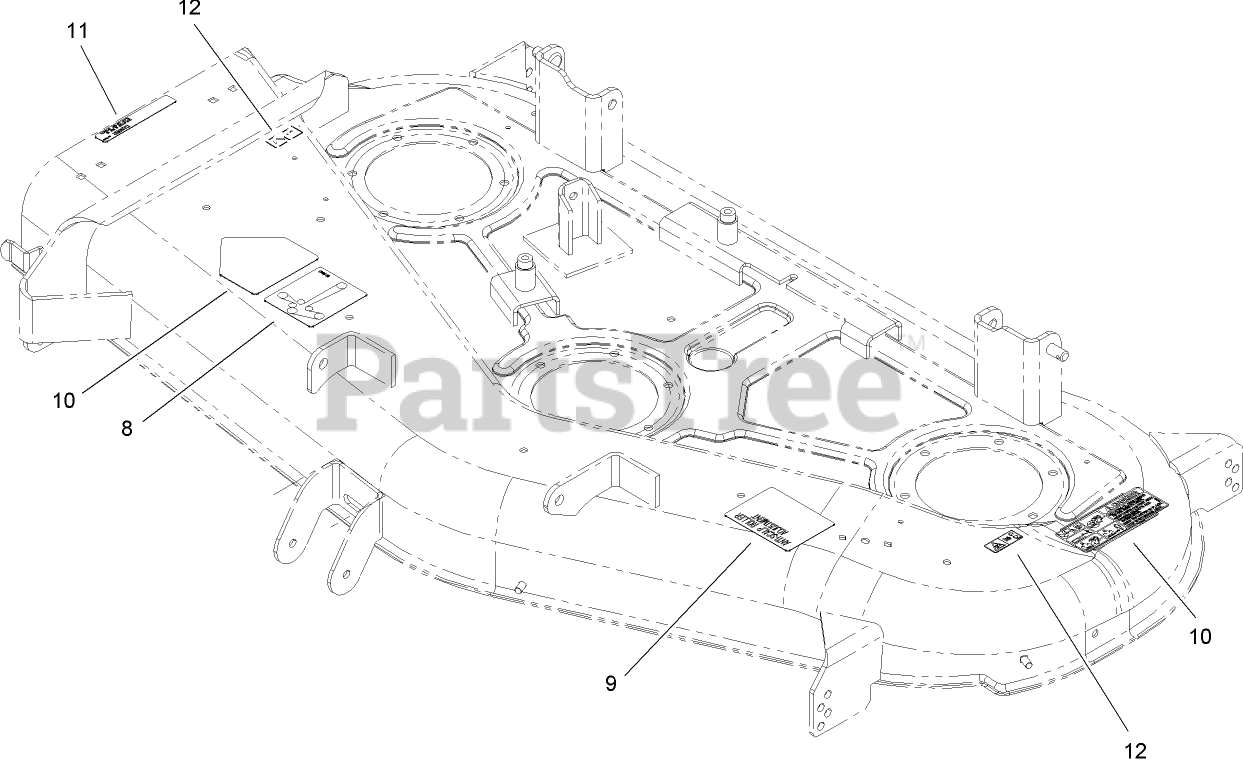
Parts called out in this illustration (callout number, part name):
8	DECAL-ROUTING, BELT
9	DECAL-SCALP, ANTI
10	DECAL-DANGER
11	DECAL-DANGER
12	DECAL-DANGER
